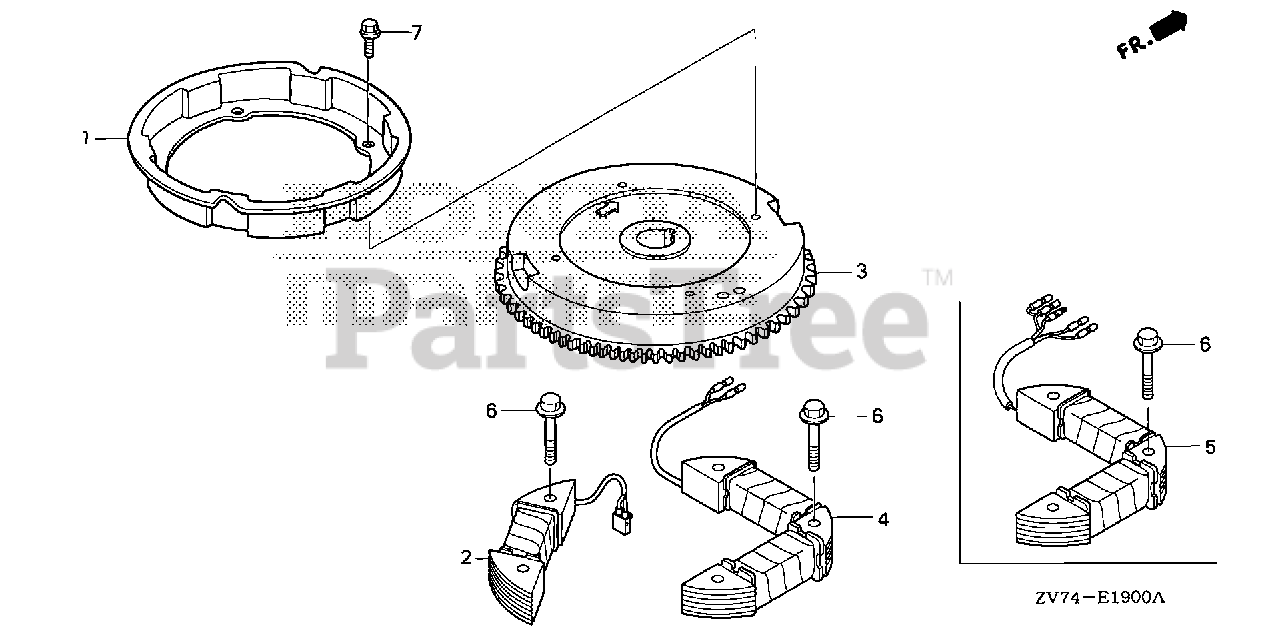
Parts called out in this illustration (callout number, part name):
1	PULLEY, STARTER
2	COIL ASSY., POWER
3	FLYWHEEL *TBLACK* (BLACK)
4	COIL ASSY., CHARGE (12V-10A)
6	BOLT, FLANGE (6X35) (CT200)
7	BOLT, FLANGE (6X12)
